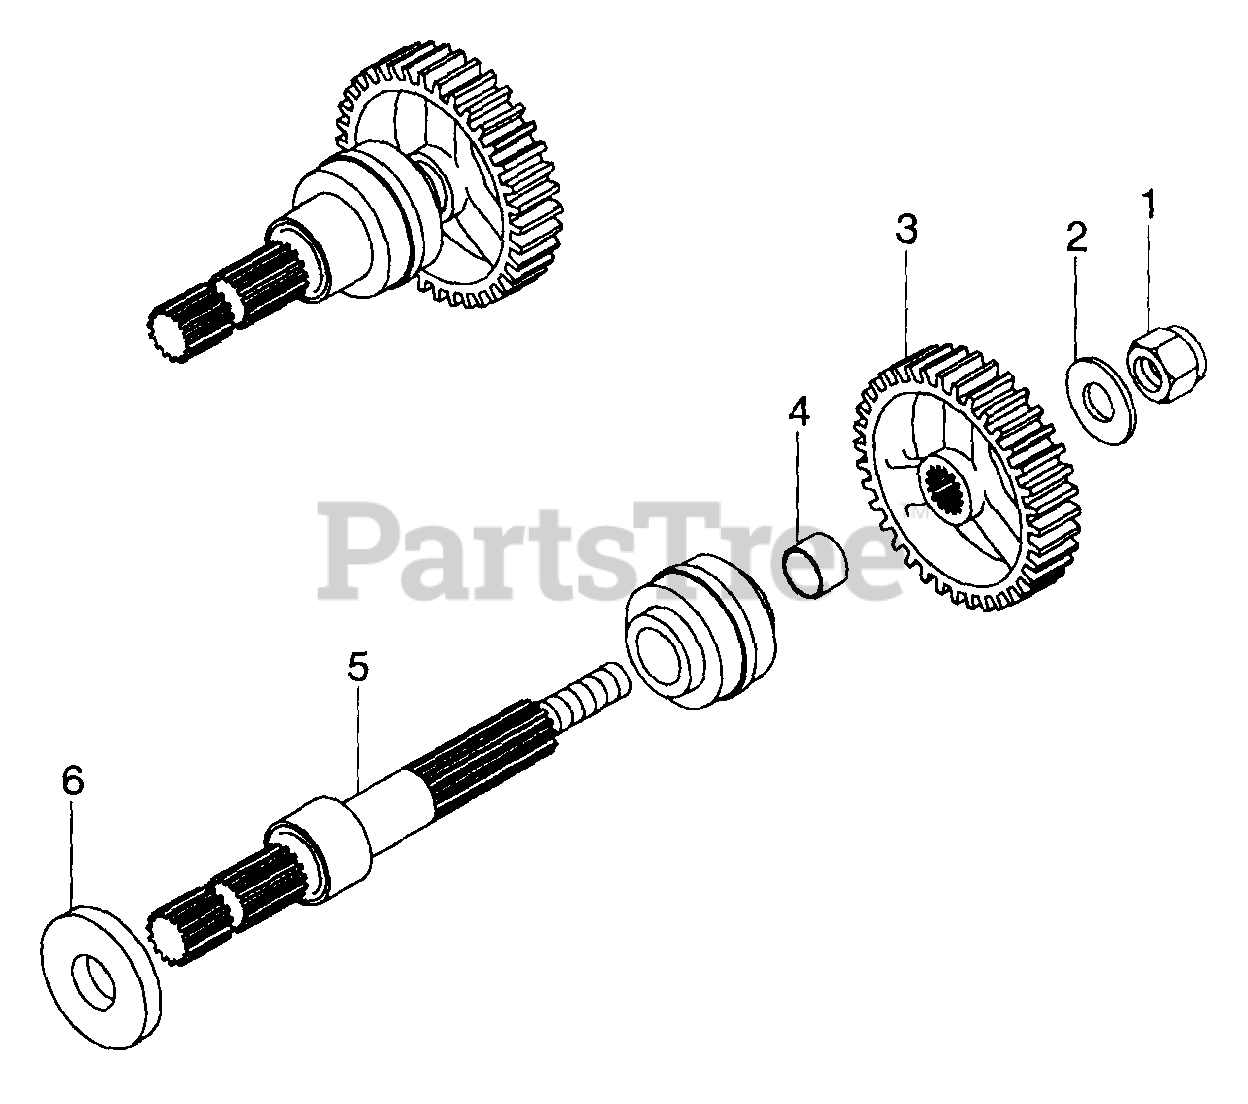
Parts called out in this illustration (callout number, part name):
1	Nut-Locking-Nylon .250-20 Grade 2
2	Washer-Flat-Steel .687 x 1.312 x .135
3	Gear, Spur PTO 10 DP 56 T
4	Bushing-Sleeve 1.06 x 1.38 x 1.38
5	Shaft, PTO
6	Seal, 1.375 x 2.129 x 3.15
